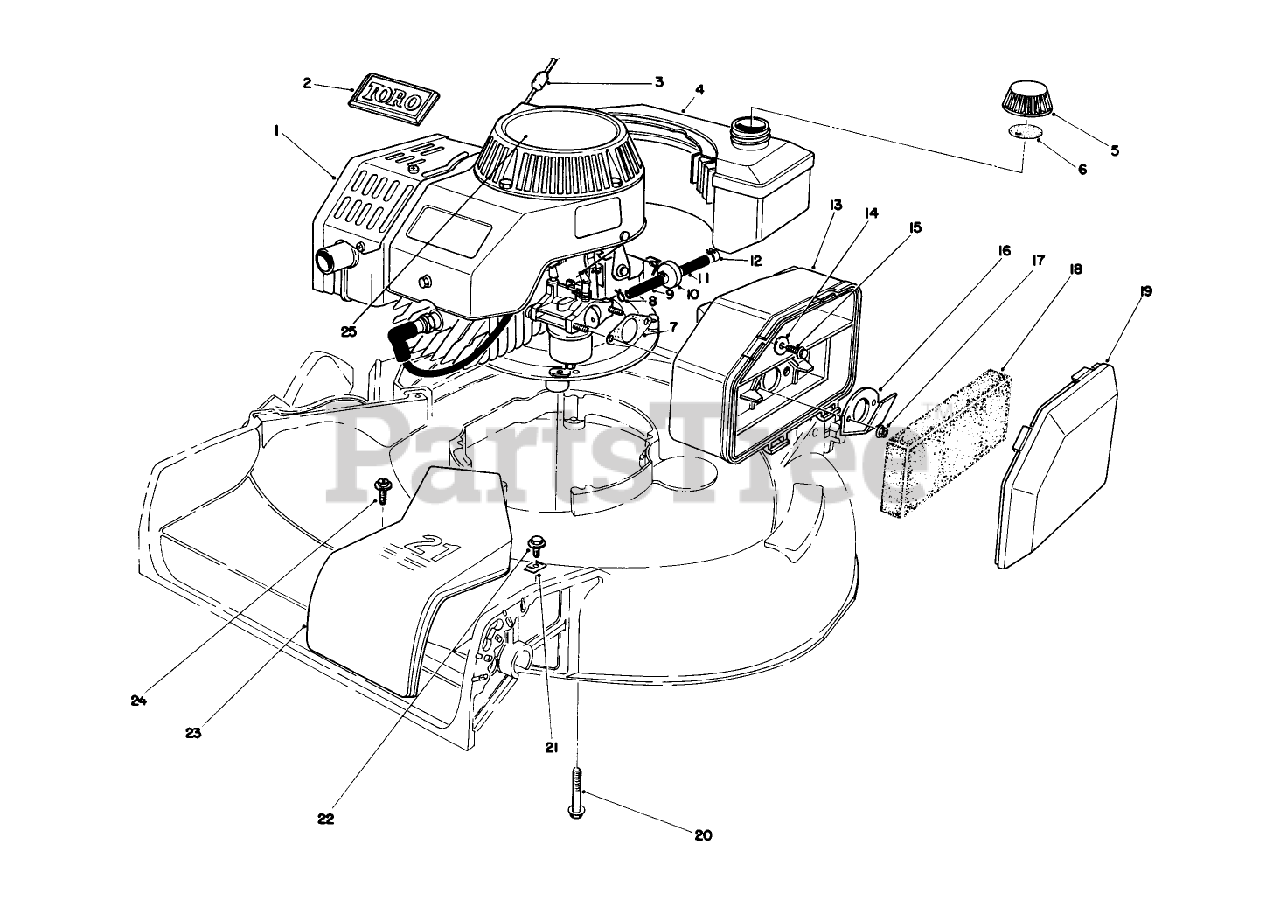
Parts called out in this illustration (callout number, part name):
3	STOP-ROPE
5	GAS CAP ASM 50:1
6	GAS CAP GASKET
7	GASKET-AIR CLEANER
8	CLAMP-HOSE
9	HOSE-FUEL
10	FILTER-FUEL
11	HOSE-FUEL
12	CLAMP-FUEL LINE
13	AIR CLEANER
14	WASHER-FLAT
15	SCREW-HH
16	SPIT BACK DEFLECTOR
18	FILTER
22	SCREW-THD ROLL, HWH
23	BELT COVER 21" S D
24	SCREW
